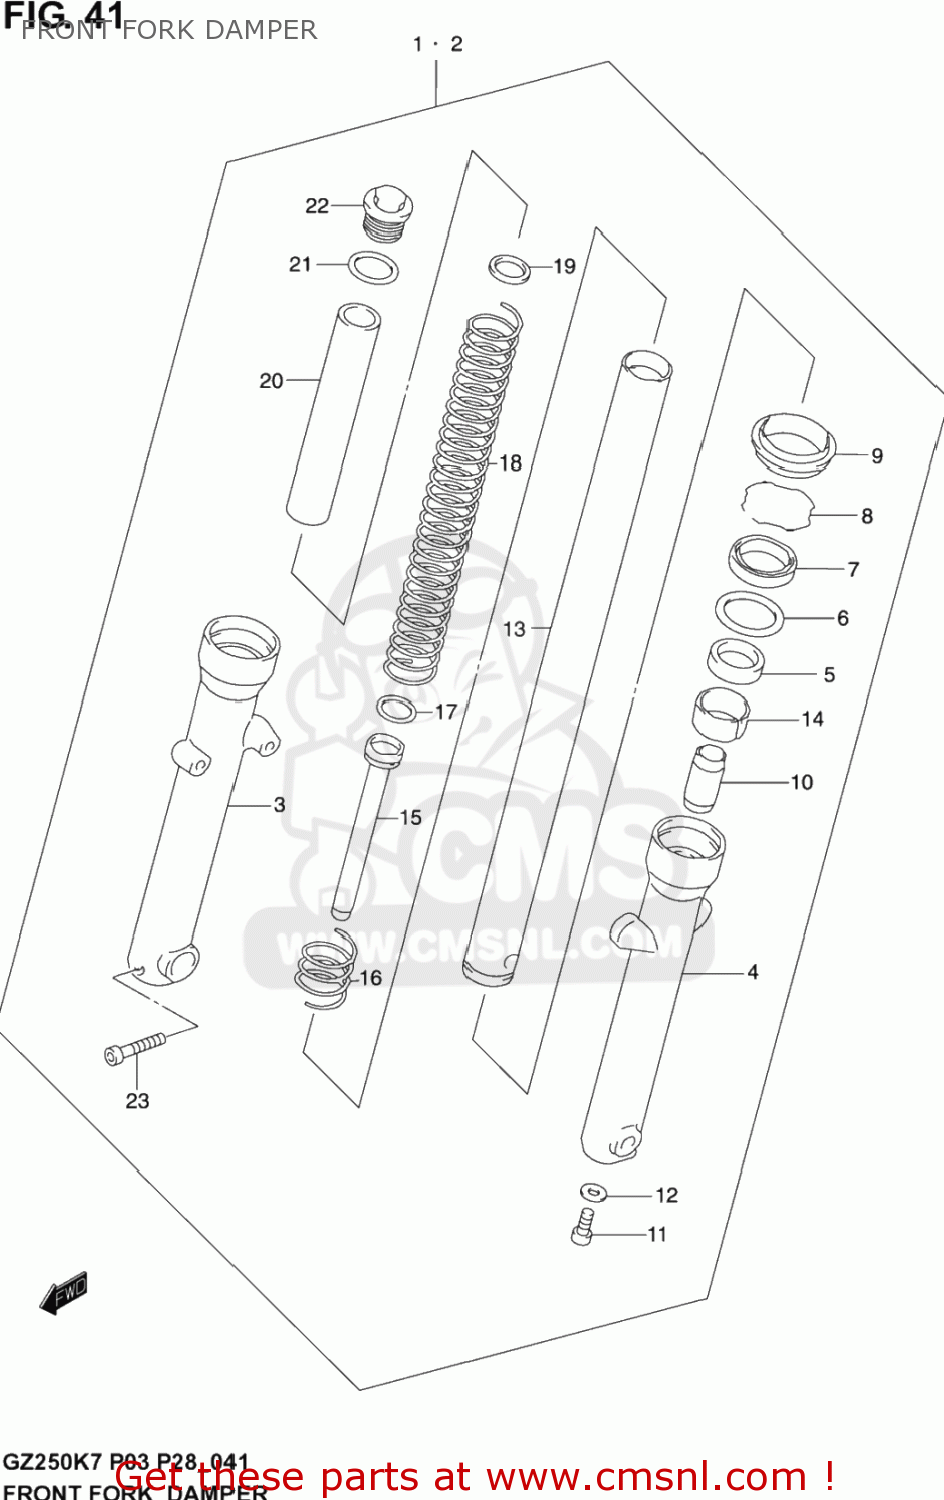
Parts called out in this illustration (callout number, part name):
1	DAMPER ASSY,FR FORK,R
2	DAMPER ASSY GZ
3	TUBE OUTER R
4	TUBE, OUTER LH
5	BUSHING,GUIDE
6	SPACER, SEAL
7	OIL SEAL,FRONT FORK
8	RING, STOPPER
9	SEAL, DUST
10	PIECE, OIL LOCK
11	BOLT,CENTER (8X18)
12	GASKET (NAS)
13	INNER TUBE
14	BUSH,SLIDE
15	PIPE,SEAT
16	SPRING,REBOUND
17	RING,PISTON
18	SPRING,FR
19	JOINT,SPRING
20	COLLAR, SPRING
21	O RING
22	BOLT,FR FORK
23	BOLT
